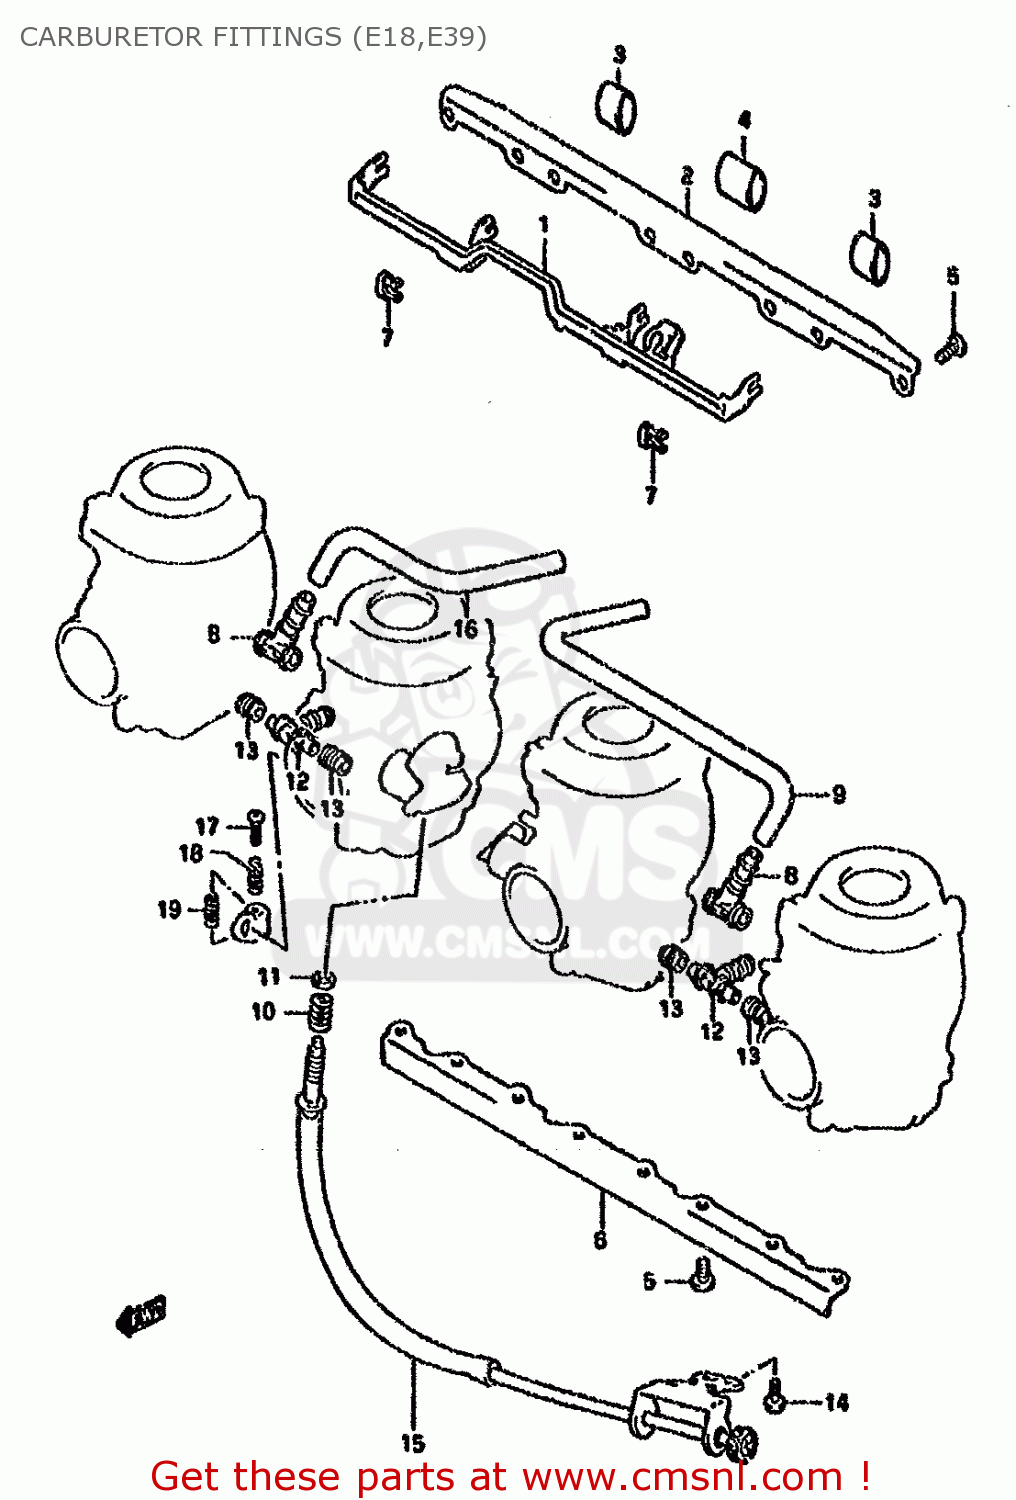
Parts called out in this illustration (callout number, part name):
1	LEVER,STARTER
2	PLATE
3	HOSE(16X19X100)
4	HOSE(16X19X100)
5	SCREW
6	PLATE
7	HOLDER
8	HOSE
9	HOSE
10	SPRING
11	WASHER
12	NIPPLE
13	SEAL
14	SCREW
15	ADJUSTER ASSY
16	HOSE
17	SCREW
18	SPRING
19	SPRING
20	SPRING
21	HOSE
